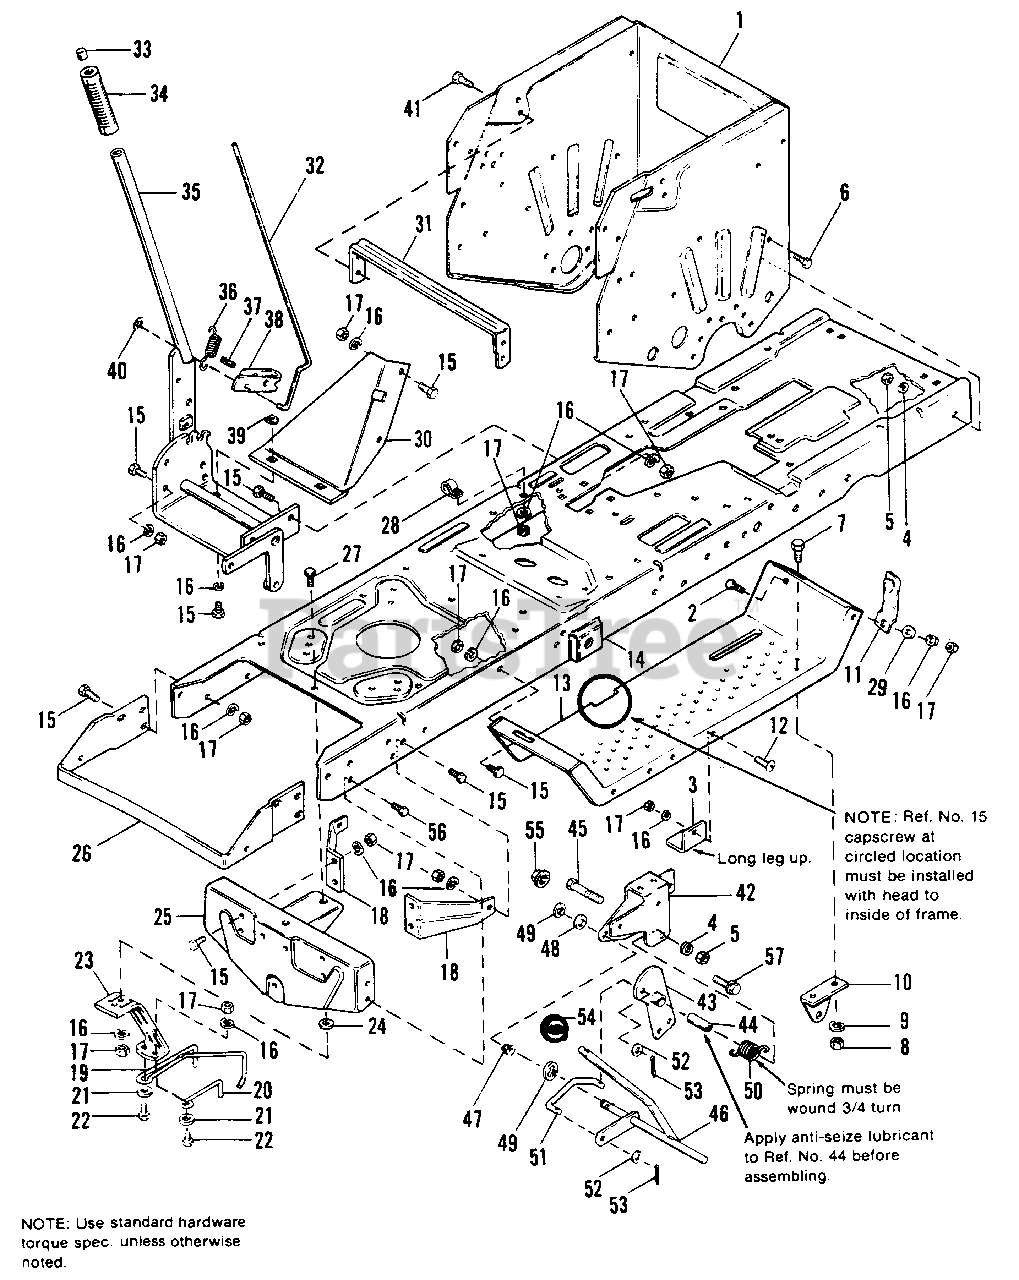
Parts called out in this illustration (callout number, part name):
1	SUPPORT, Axle Wrapper
2	BOLT, Carriage, 5/16-18 x 3/4
3	UP-STOP, Mower
4	LOCKWASHER, 3/8
5	NUT, Hex, Full, 3/8-16
6	CAPSCREW, Hex, 3/8-16 x 3/4
7	CAPSCREW, Hex, 1/4-20 x 5/8
8	NUT, Hex, Full, 1/4-20
9	LOCKWASHER, 1/4
10	SUPPORT, Clutch
11	LATCH ASSY.
12	SCREW, Truss Hd., Slotted, 5/16-18 x 3/4
14	FRAME (Except Mfg. No. 1690927 & 1690930)
14	FRAME (Mfg. No. 1690927 & 1690930 Only)
15	CAPSCREW, Hex, 5/16-18 x 3/4
16	LOCKWASHER, 5/16
17	NUT, Hex, Full, 5/16-18
18	BRACE, Axle Support
21	WASHER, Plain, 1/4
22	CAPSCREW, 5/16-18 x 7/8
23	SUPPORT, Belt Guide
24	WASHER, Plain, 11/32
25	SUPPORT ASSY., Axle
26	SUPPORT, Hood
27	CAPSCREW, Hex, 5/16-18 x 1
29	WASHER, 5/16 Std.
30	BRACE, Lift
31	BRACE, Seat
34	GRIP
35	LEVER ASSY., Lift
37	PIN, Spring, 3/8 x 1
38	LATCH, Lever
39	NUT, Speed, 5/16-18
41	SCREW, Taptite, 5/16-18 x 1/2
42	BRACKET, P.T.O.
43	ARM ASSY., P.T.O. Rod
45	CAPSCREW, Hex, 3/8-16 x 2-1/4
46	HANDLE ASSY., P.T.O.
47	BUSHING, Split
49	RING, Snap
50	SPRING, Torsion
51	LINK, P.T.O.
53	PIN, Cotter, 3/32 x 3/4
55	NUT, Flange, Whizlock, 1/4-20
56	SCREW, Taptite, 5/16-18 x 3/4
57	CAPSCREW, Hex, Wash. Hd., 1/4-20 x 5/8
